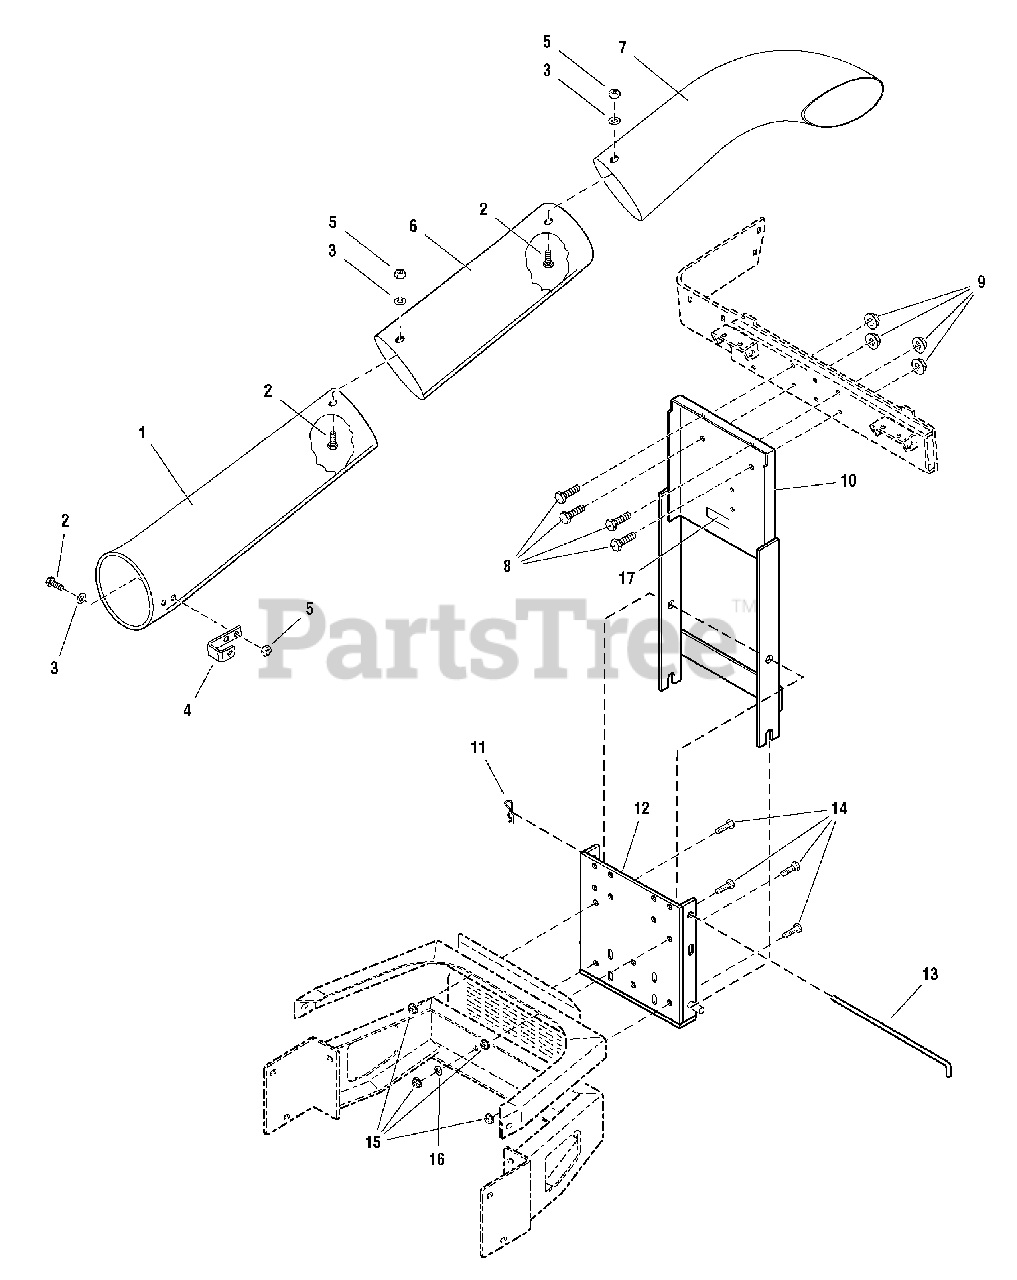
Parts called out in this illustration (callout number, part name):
1	CHUTE, Grass Catcher Lower, Black
2	SCREW, Truss Head Phillips, #10-24 x 3/4 Black
3	WASHER, 3/16 (0.187ID x 0.75OD x .06THK) Black
4	CLIP, Spring, 1.40 x 1.48OP x 3.50LG 0.88WD
5	NUT, Hex Lock, 10-24 with Nylon Insert, NC3B Black
6	CHUTE, Grass Catcher Middle, Black
7	ELBOW, Vacuum Collector, 5.57ID 30.29LG .090
8	CAPSCREW, Hex Head, 3/8-16 x 3/4 G5 Black
9	NUT, Hex Flange Whiz Lock, 3/8-16 Large Black
10	FRAME ASSEMBLY, Bagger
11	CLIP, Hair Pin, .125DIA Spring Wire, 2.562LG Black
12	FRAME ASSEMBLY, Bumper Mounting
13	ROD, Support, .625DIA 13.0LG
14	CAPSCREW, Hex Head, 1/2-13 x 1-1/4 G5 Black
15	NUT, Hex Flange Whiz Lock, 1/2-13 Black
16	WASHER, 1/2 (0.53ID x 1.25OD x .08THK) Black
17	DECAL, ID Plate
